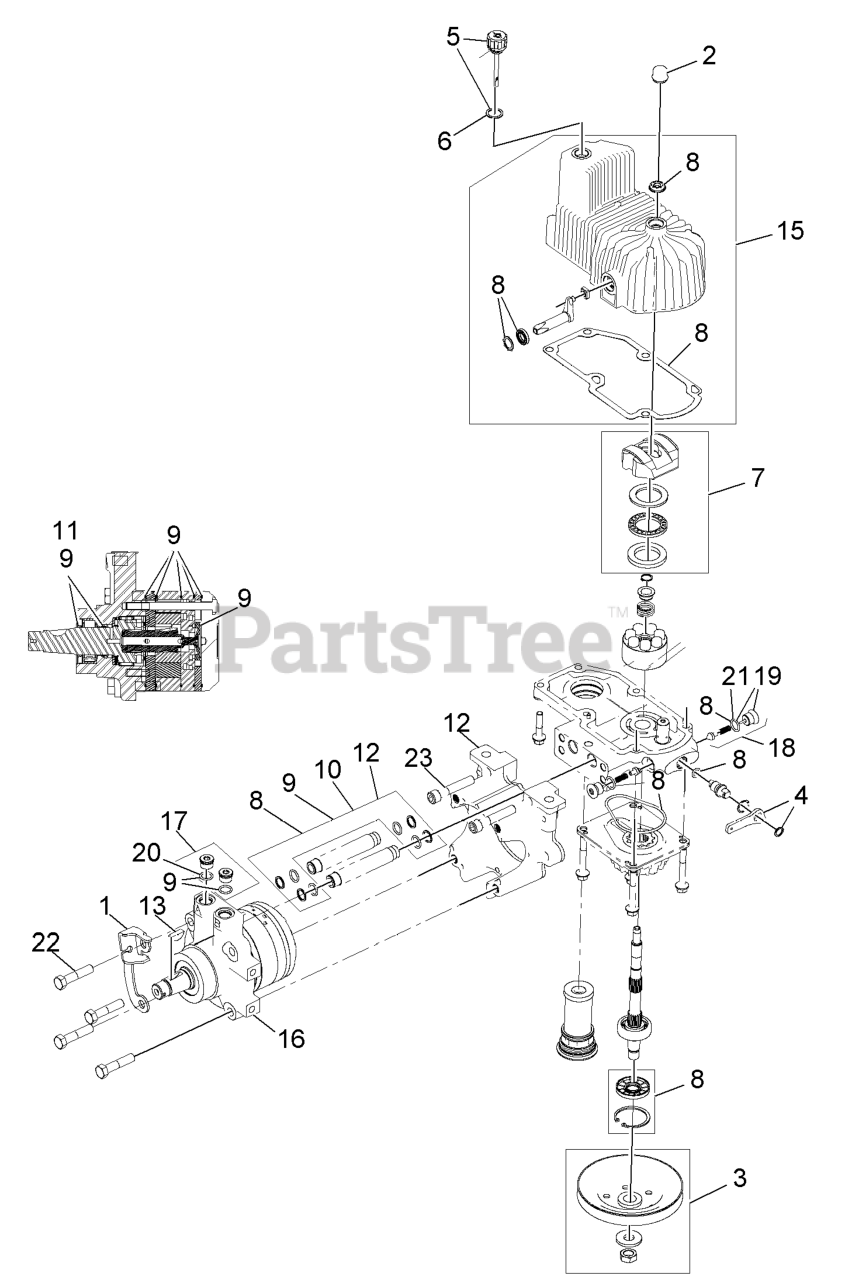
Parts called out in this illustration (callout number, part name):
1	BRACKET-ANCHOR, CABLE
2	COVER-SHAFT, HYDRO
3	PULLEY KIT
4	HANDLE-BYPASS VALVE, HYDRO
5	DIPSTICK-HYDRO W/GASKET
6	GASKET-DIPSTICK, HYDRO
7	SWASH BLOCK KIT
8	PUMP SEAL KIT
9	MOTOR SEAL KIT
10	TUBE SEAL KIT
11	OUTPUT SHAFT SEAL KIT
12	NOSE CUP-UHT
13	KEY-WOODRUFF
15	HOUSING-HYDRO, LH
16	MOTOR-HYDRAULIC LH 240CC
17	MAGNETIC PLUGS SERVICE KIT
18	CHECK VALVE ASM
19	PLUG-CHECK (W/O-RING)
21	O-RING-CHECK VALVE
22	SCREW HH
23	SCREW-HSH
